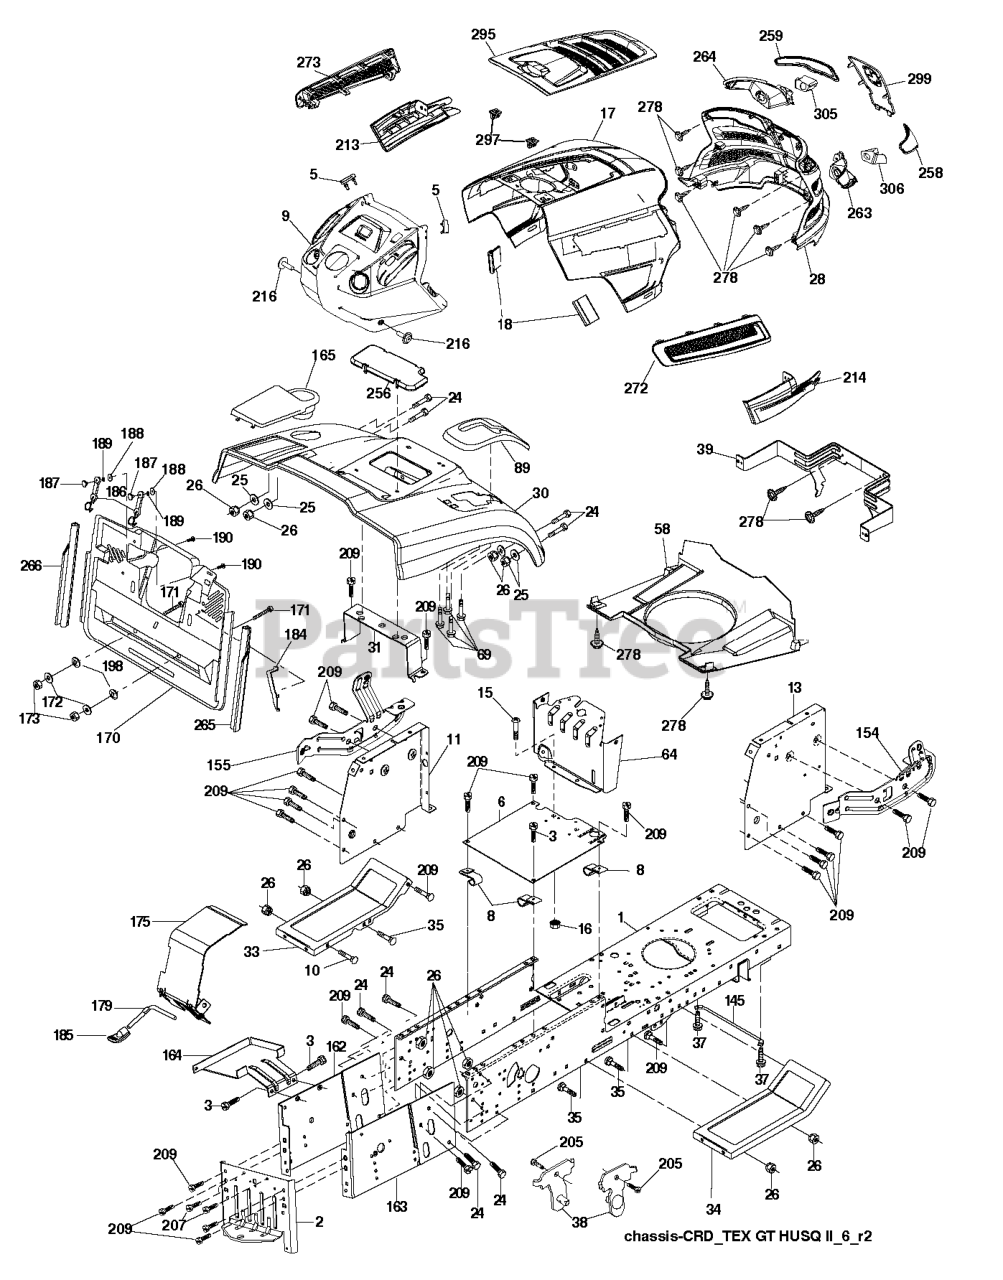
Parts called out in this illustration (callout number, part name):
2	DRAWBAR
3	SCREW 3/8-16X3/4
5	BUMPER DASH
6	PLATE
8	CLIP,INSULATOR
9	DASH.UPPR.GT2.CRD.SM.PTO.MC.HR
10	BOLT D
11	PANEL DASH LH
13	PANEL DASH RH
15	Screw, Machine, Truss Head 5/16-18 UNC x 3/4
16	NUT
17	HOOD.ASM.HUSQVARNA.GT.TEX.ORAN
18	BUMPER.HOOD.TEX.HUSQVARNA
25	WASHER
26	NUT
28	GRILLE.SUBSTRATE.2011.
30	FENDER.PNT.CRD.MS-668
31	BRACKET SUPPORT FENDER
33	FOOTREST.PNT.LH.GREY
34	FOOTREST.PNT.RH.GREY
37	Screw 5/16-18 x 1/2 Hex, Self Tapping 5/16-18 x 1/2
38	BRACKET ASM PIVOT MOWER REAR
39	BRACKET.PIVOT.HOOD.GT.HUSQ.II
58	AIR.DUCT.GTV.BLACK
69	SCREW.HI-LO.CONSOLE
89	CONSOLE.CRD.AUTO.GRY
145	ROD.PIVOT.HOOD
162	BRACKET
163	BRACKET EXTEN CHASSIS RH CRD
165	COVER.BATTERY.BAG.ELE.CRD.498
172	WASHER
175	DOOR TRAP
179	ROD PIVOT FBI
184	BRACKET.ACTUATOR.BAGGER.SRD
185	KNOB.BRAKE.PARKING.ROD
186	LATCH ASSY
187	WELDNUT
189	LOCKWASHER #10
190	SCREW
207	SCREW, 5/16-18 X 1/2
209	SCREW, 3/8-16X3/4
213	SIDE.TRIM.LH.GT.HUSQ.II.GRAY
214	SIDE.TRIM.RH.GT.HUSQ.II
216	SCREW 14-20 X 5/8
256	COVER FENDER CRD
258	LENS.HEADLIGHT.RH.GTII.2011
259	LENS.HEADLIGHT.LH.GTII.2011
263	BEZEL LIGHT.RH.GT.II.MYLAR
264	BEZEL LIGHT.LH.GT.II.MYLAR
265	SEALING
266	SEALING
272	VENT.SIDE.RH.GT.HUSQ.II.
273	VENT.SIDE.LH.GT.HUSQ.II.498
278	SCREW.#10 X 0.750.BOS
295	VENT.ASM.TOP.GT.HUSQ.II.GREY
297	CLIP.RETAINER.TINNER.
299	APPLIQUE.SUBASM.GT.HUSQ.II
305	INSERT.REFLECTIVE.LH.HUSQ.GTII
306	INSERT.REFLECTIVE.RH.HUSQ.GTII
